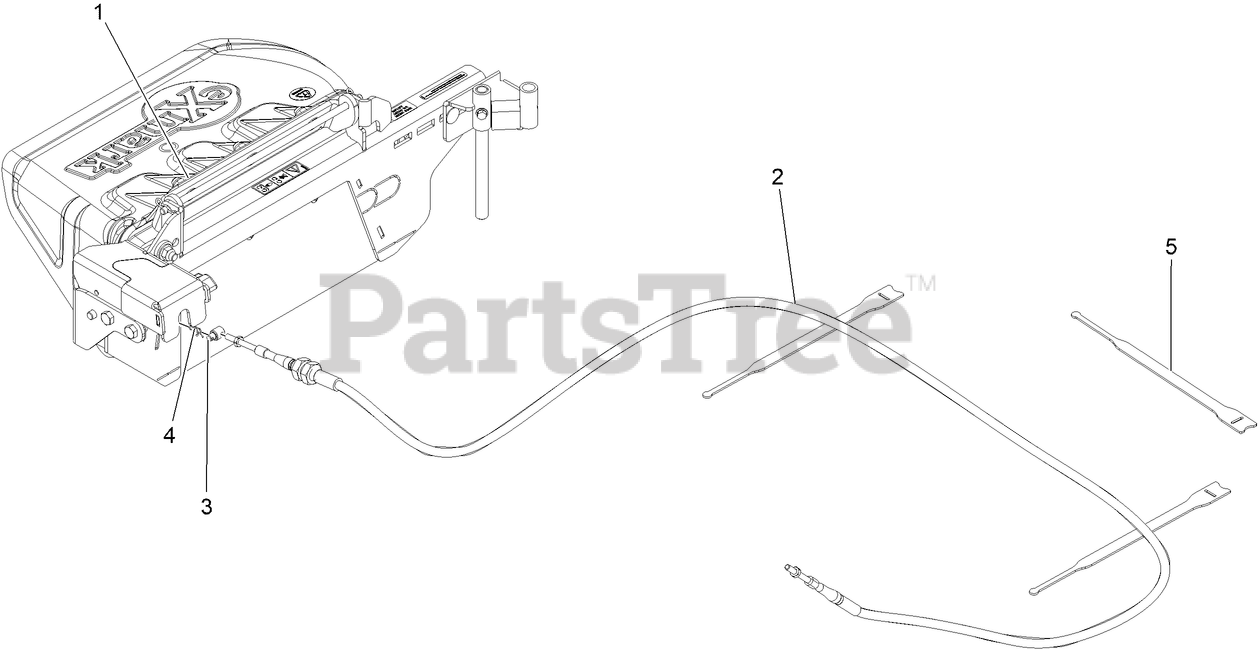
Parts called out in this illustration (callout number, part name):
1	ASM, OCD
2	CABLE-DISCHARGE GATE
3	PIVOT, CONTROL CABLE
4	PIN-COTTER, LOCKING
5	STRAP-VELCRO, CABLE TIE
